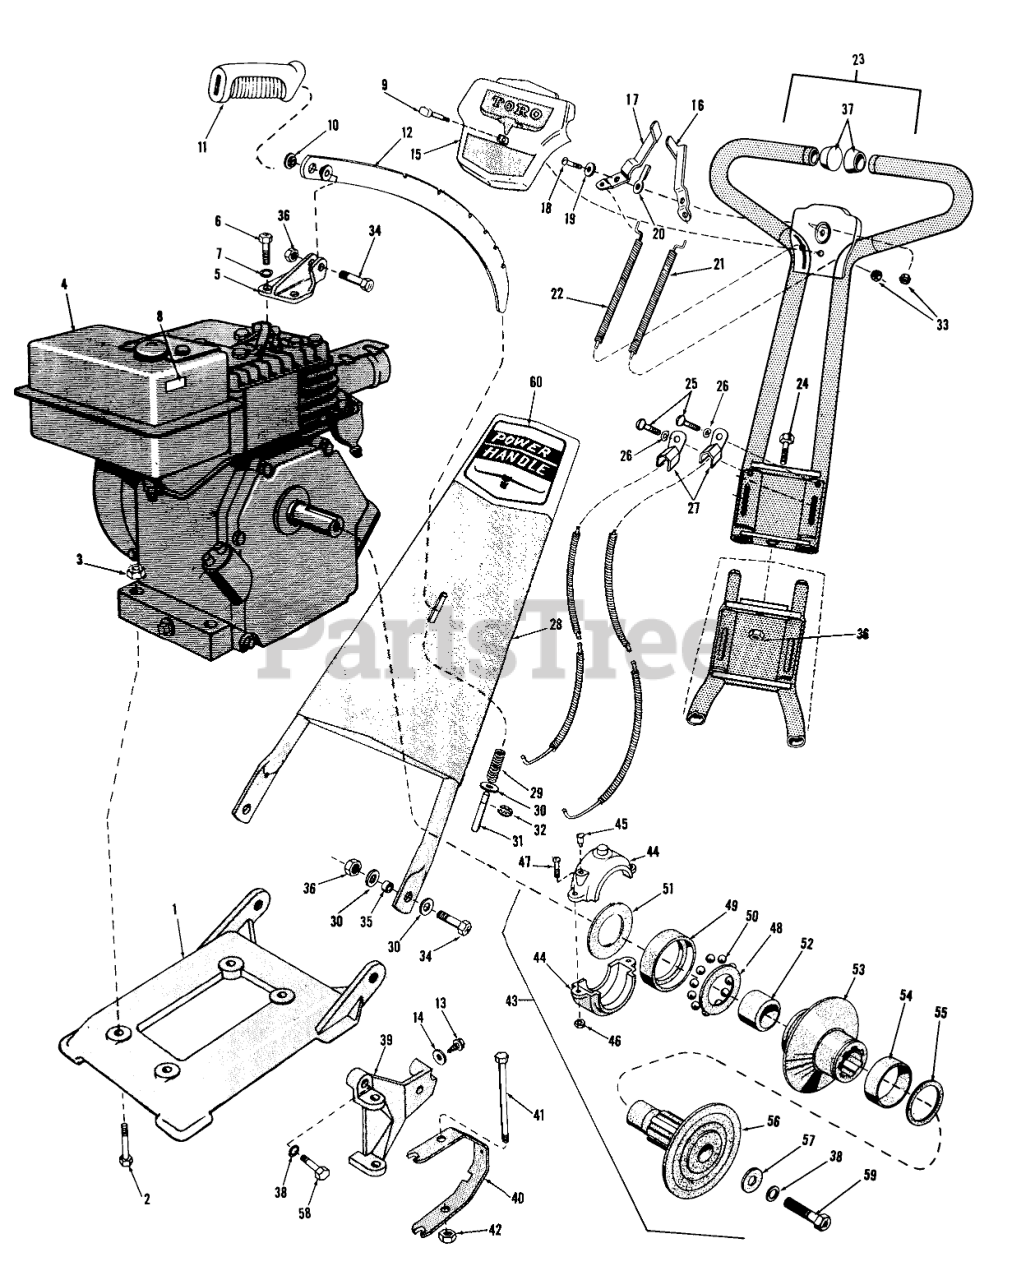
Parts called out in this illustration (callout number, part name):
1	Engine Base
2	SCREW-HH
3	NUT-LOCK NI
4	Engine
5	Bracket, Handle
6	Screw
7	WASHER-LOCK
8	Decal
9	Screw
10	GROMMET
11	Grip Handle
12	Bar Adjustment
13	SCREW-HWH
14	WASHER-FLAT
15	Escutcheon Plate
16	Clutch Lever
17	Throttle Lever
19	WASHER CONTROL PIVOT
20	Washer
21	Throttle Control Assy.
22	CLUTCH CONTROL ASM
23	Upper Handle Assy.
24	SCREW-HH
25	SCREW-PPH
26	WASHER-LOCK
27	Clamp
28	Lower Handle Assy.
29	SPRING
30	WASHER-PLAIN
32	RING-RETAINING, EXT
33	NUT-LOCK, NI
34	SCREW-HH
35	Grommet
36	NUT-LOCK, NI
37	Button Plug
38	WASHER-LOCK
39	Bracket, Mounting
40	Shift Fork
41	SCREW-HH
42	NUT-LOCK NI
43	Clutch Assy.
44	Ring, Slip Kit,
45	OILER
46	NUT-LOCK
47	SCREW
48	Check Washer
49	Ball Race
50	Ball
51	Washer-Thrust
52	Inner Ball Race
53	Sliding Flange
54	IDLER BUSHING
55	1-1/2X048 EX MED RING
56	Body, Clutch
57	Washer
58	SCREW-HH
59	SCREW-HH
60	Decal
